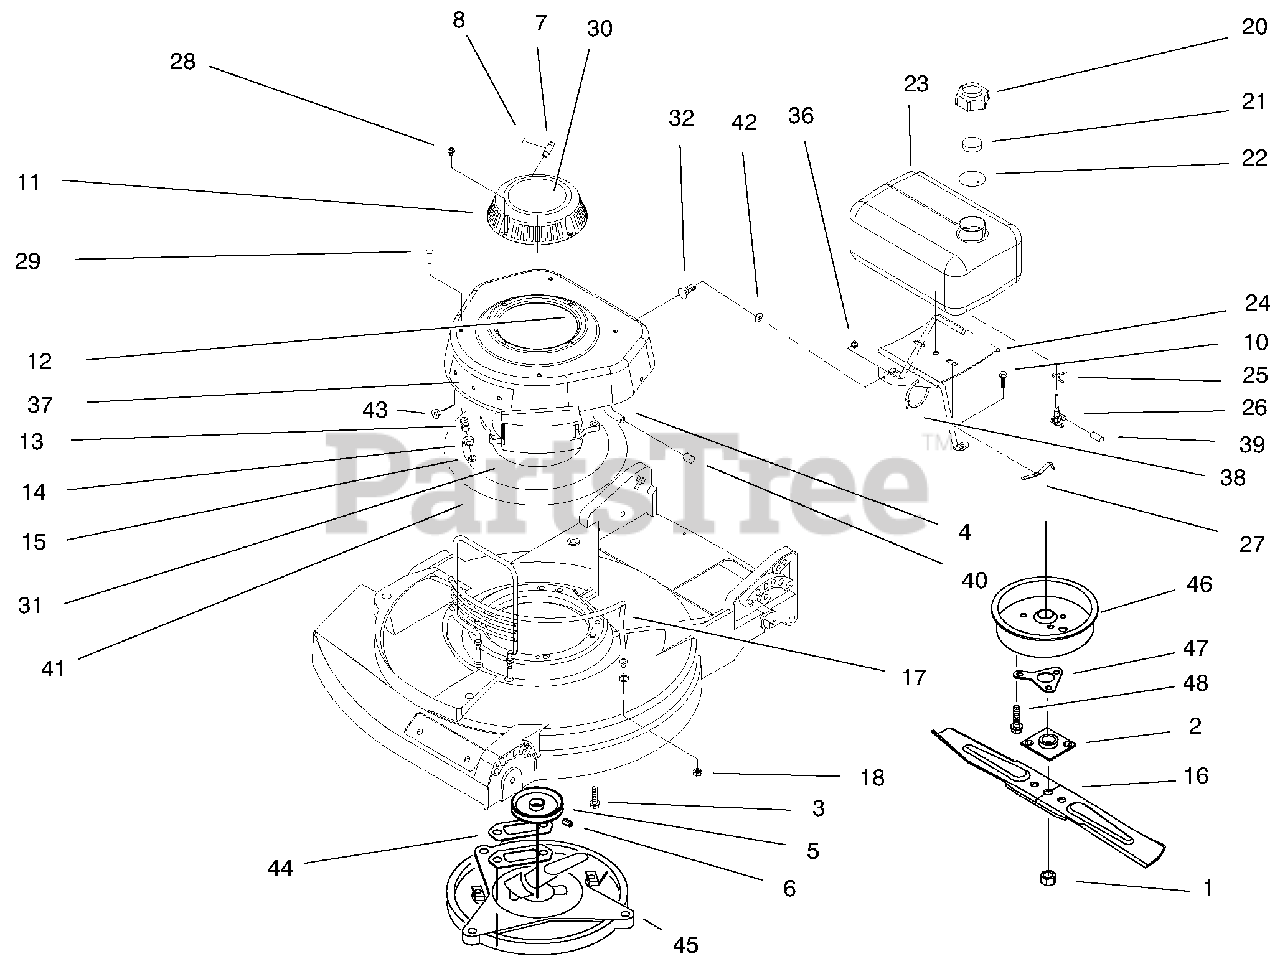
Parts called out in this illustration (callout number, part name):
1	Nut-Blade
2	Plate & Collar Assembly
3	Screw-Engine Mount
4	Hose-Gas
6	Screw-Set
7	Rope-Stop
8	Staple
10	Screw-Hex Washer Hd.
11	Housing-Starter
12	Shroud Assembly
14	Actuator-Brake Lever
15	Retainer
16	Blade-53cm
17	Guard-Engine
18	Nut-Lock
20	Cap-Fuel
21	Foam-Baffle
23	Tank-Fuel
24	Leg & Saddle Assembly
25	Clamp-Hose
26	Valve & Screen
28	Screw-Sems
29	Screw-Thr'd Form
30	Decal-Recoil
31	Engine-2 Cycle
32	Screw-Carriage
36	Nut-Lock
37	Applique
38	Tie-Strap
39	Plug-Fuel Valve
40	Plug-Fuel Line
41	Plate-Engine
42	Washer-Flat
43	Retainer-Applique
44	Gasket-Muffler
45	Plate-Muffler
46	Muffler Cover Assembly
47	Support-Crankshaft
